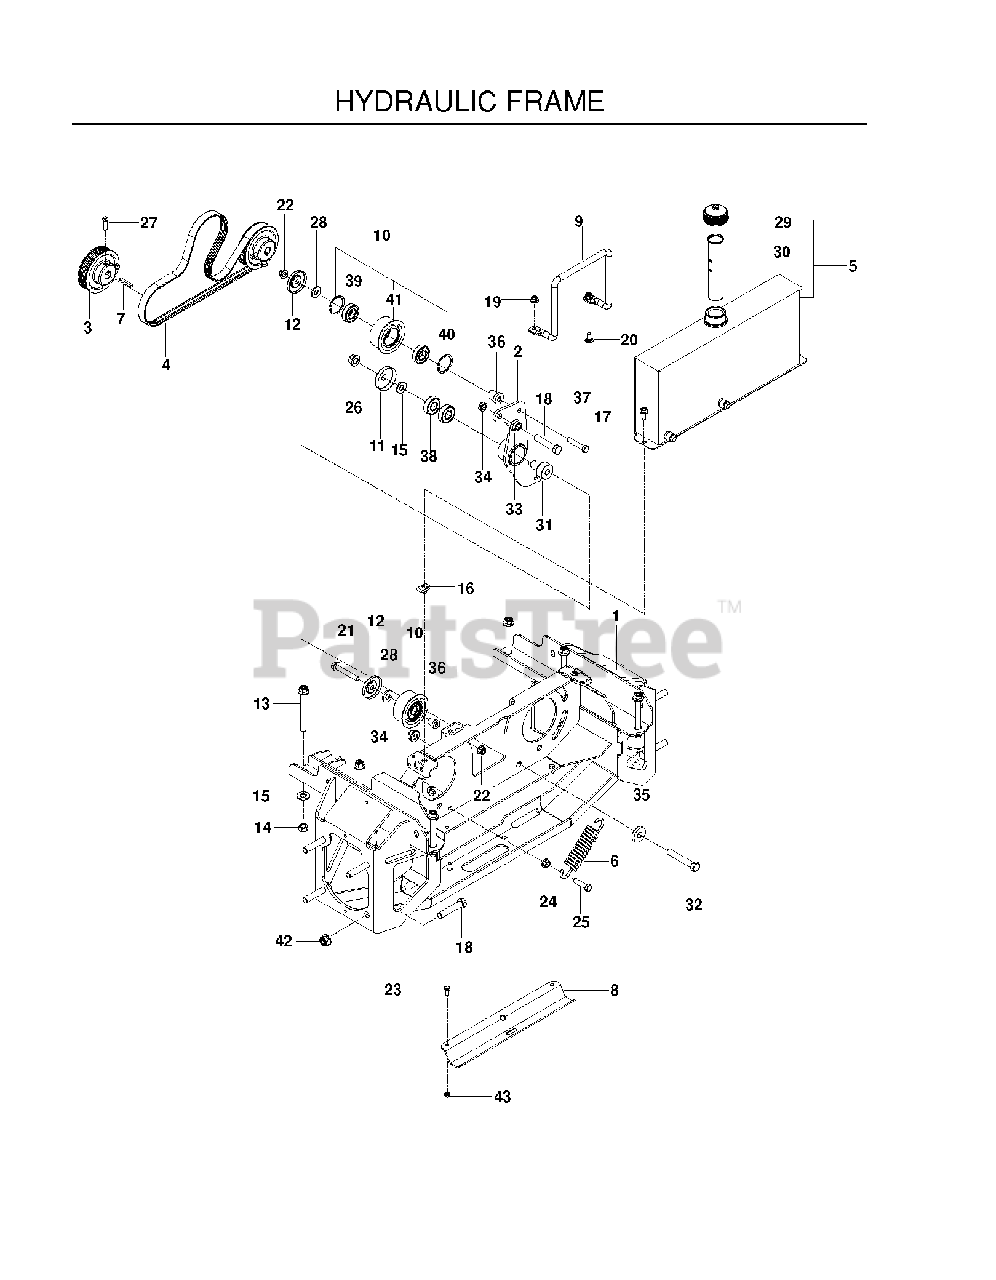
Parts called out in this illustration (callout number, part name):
1	WELDMENT, PUMP BAY, BLK
2	ASSEMBLY.IDLER.W/BEARINGS
3	PUMP SHEAVE
4	BELT, PUMP
5	ASSEMBLY, RESERVOIR
7	KEY, METRIC
8	GUARD, HOSE
9	GUIDE, BELT
10	IDLER, W/BEARINGS
11	SHIELD, DUST
12	DUST SHIELD
13	BOLT 7/16 X 4 GR 8 BLK PHOS
14	7/16-14 HEX NUT W/NYL RING ZD
15	WASHER 1/2" FLAT
16	U-CLIP 5/16-18 NUT RETAINER
17	HHFS 5/16-18 X 3/4
18	HEX SCREW 1/2-13 X 2.5" GR 5
19	5/16-18 NYLOC FLANGE NUT
20	BOLT 5/16C X 3/4" CARRIAGE
21	HHFS 3/8-16 X 2 3/4
22	NUT 3/8-16 HEX FLG NYLOC ZD
23	HCS 1/4C X 5/8
24	NUT 3/8C WHIZ
25	HCS 3/8-16 X 1-1/2
26	NUT, 1/2-13 HEX FLG NYLOC ZD
27	SCREW 5/16C X 1 SQ HEAD SET
28	RP WASHER 3/8 FLAT
29	CAP, HYDRAULIC
30	TUBE, ANTI-SPLASH
31	PIVOT, BEARING
32	SCREW, 1/2C X 3 HEX CAP
33	NUT 1/2-13 HEX
34	NUT, HEX 1/2-13 THIN W/NY
35	WASHER .525 X 1.375 X .25
36	Idler Arm Spacer
37	HCS 3/8C X 2
38	BEARING, BALL
40	RING, RETAINING, 1-5/8"
41	IDLER, PUMP
42	NUT, 1/2-13 HEX FLG NYLOC ZD
43	JAM NUT 1/4C (2 2 PW01)
